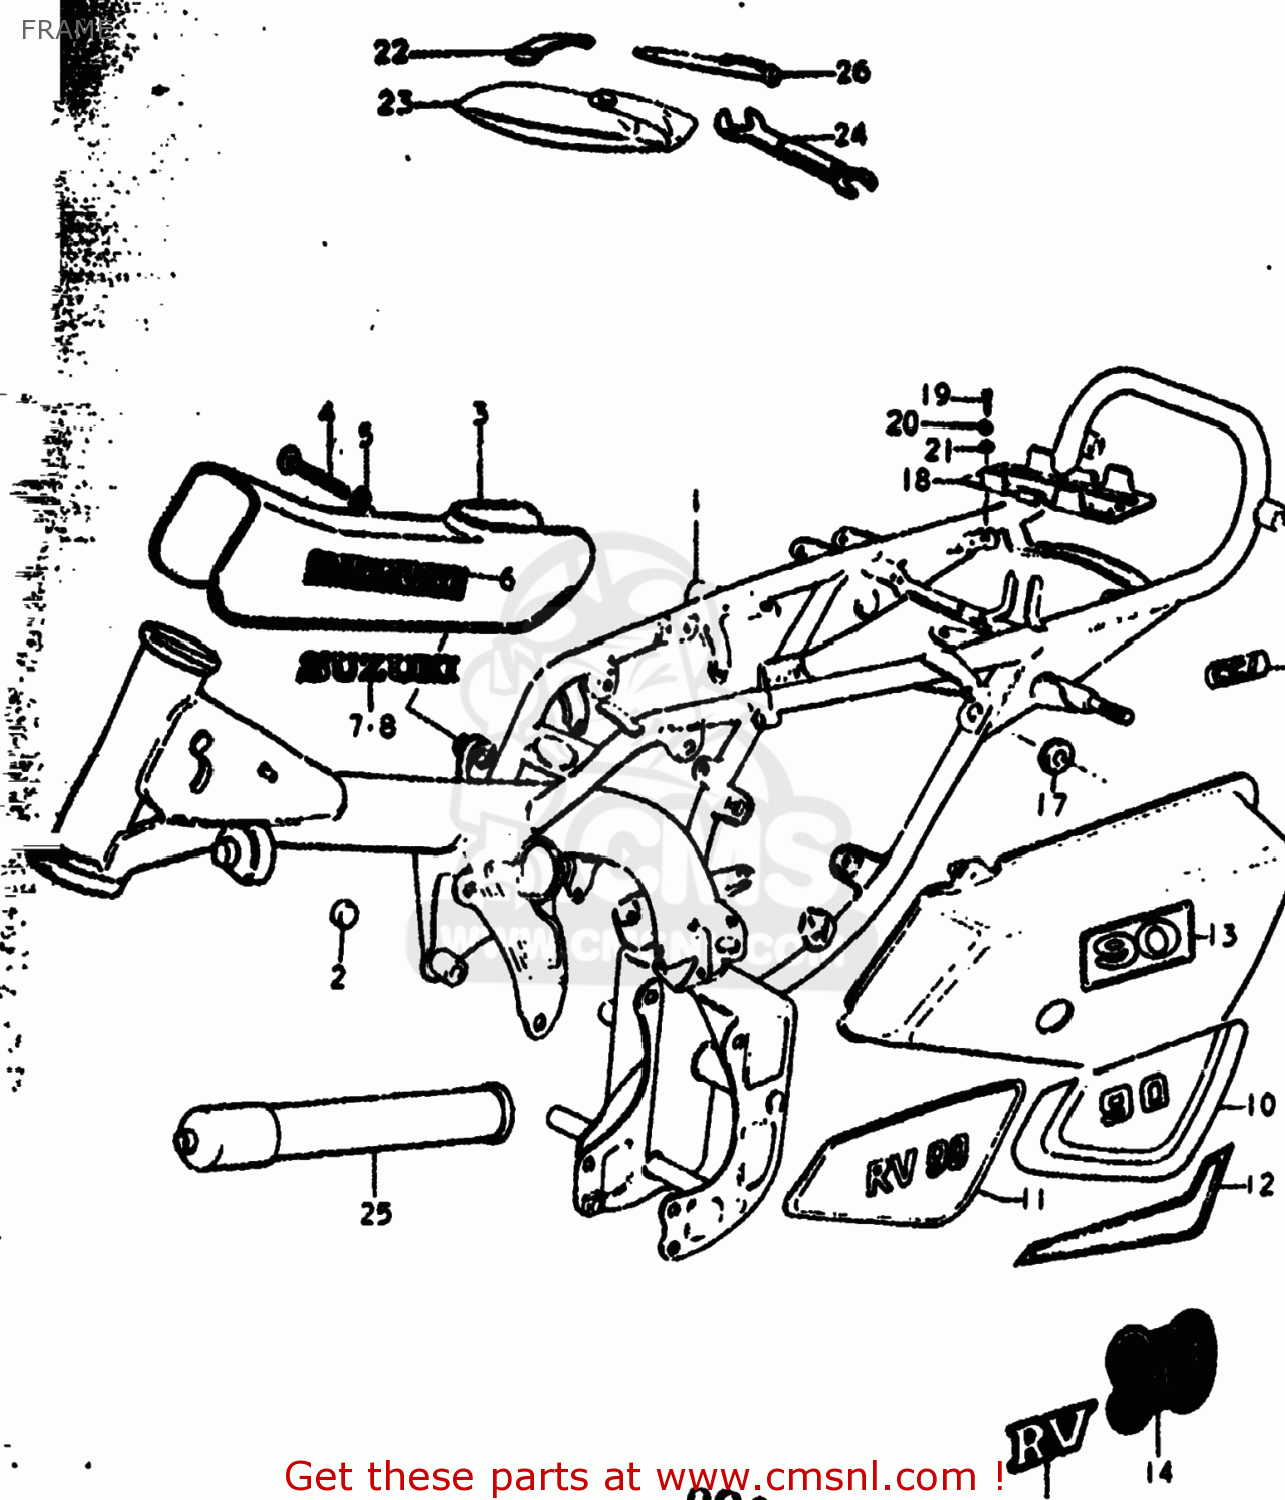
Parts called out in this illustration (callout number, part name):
1	FRAME
2	CUSHION
3	COVER
4	SCREW
5	WASHER
6	EMBLEM,SUB FUEL TANK
7	EMBLEM, FRAME COVER M,A
8	EMBLEM,FRAME COVER,FRONT
9	COVER,FRAME,LEFT
10	TAPE,FRAME COVER
11	TAPE,FRAME COVER
12	TAPE,FRAME COVER
13	EMBLEM,FRAME COVER
14	EMBLEM,FRAME COVER,LEFT
15	EMBLEM,RV
16	EMBLEM,CCIS
17	CUSHION
18	HOLDER,TOOL
19	SCREW 6X12
20	LOCK WASHER
21	WASHER 6MM
22	BAND
23	TOOL SET
24	WRENCH, CONTACT POINT
25	INFLATOR, AIR
